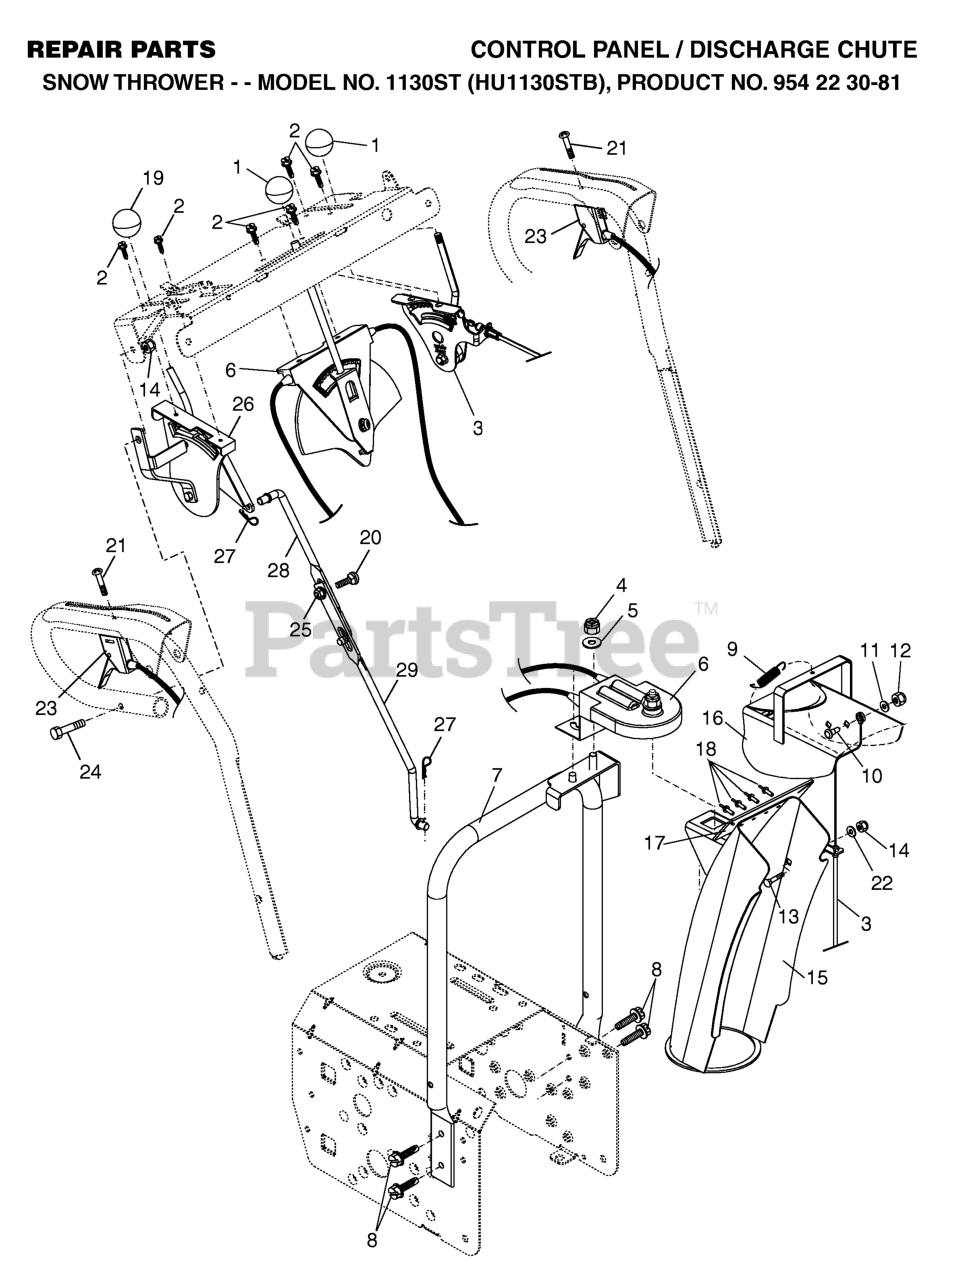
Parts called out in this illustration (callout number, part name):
1	KNOB, LEVER
2	SCREW #10-24 X 5/8
3	CONTROL ASSY, DEFLECTOR
4	NUT
5	WASHER
6	CONTROL ASSY, CHUTE ROTATER
7	SUPPORT CHUTE ROTATER
8	SELF-TAPPING SCREW 5/16-18X3/4
9	SPRING.DEFLECTOR.REM.CHUTE
10	BOLT, SHOULDER
11	WASHER
12	LOCKNUT.NYLOC.1/4-20
13	BOLT
14	NUT.71038.31-18.HEX.NYLOCK
15	CHUTE ASSY
16	DEFLECTOR.WELDMENT.PNT.ORANGE
17	SEAL, DEFLECTOR
18	RIVET BLIND
19	RP KNOB, SPEED CONTROL LEVER
20	BOLT
22	WASHER.20X8.5
23	CONTROL ASSY, POWER STEERING
25	NUT.FLANGE.5/16
26	LEVER ASSEMBLY, SPEED CONTROL
27	SPRING RETAINER
28	ROD, UPPER SPEED CONTROL
29	ROD, LOWER SPEED CONTROL.SNOW
